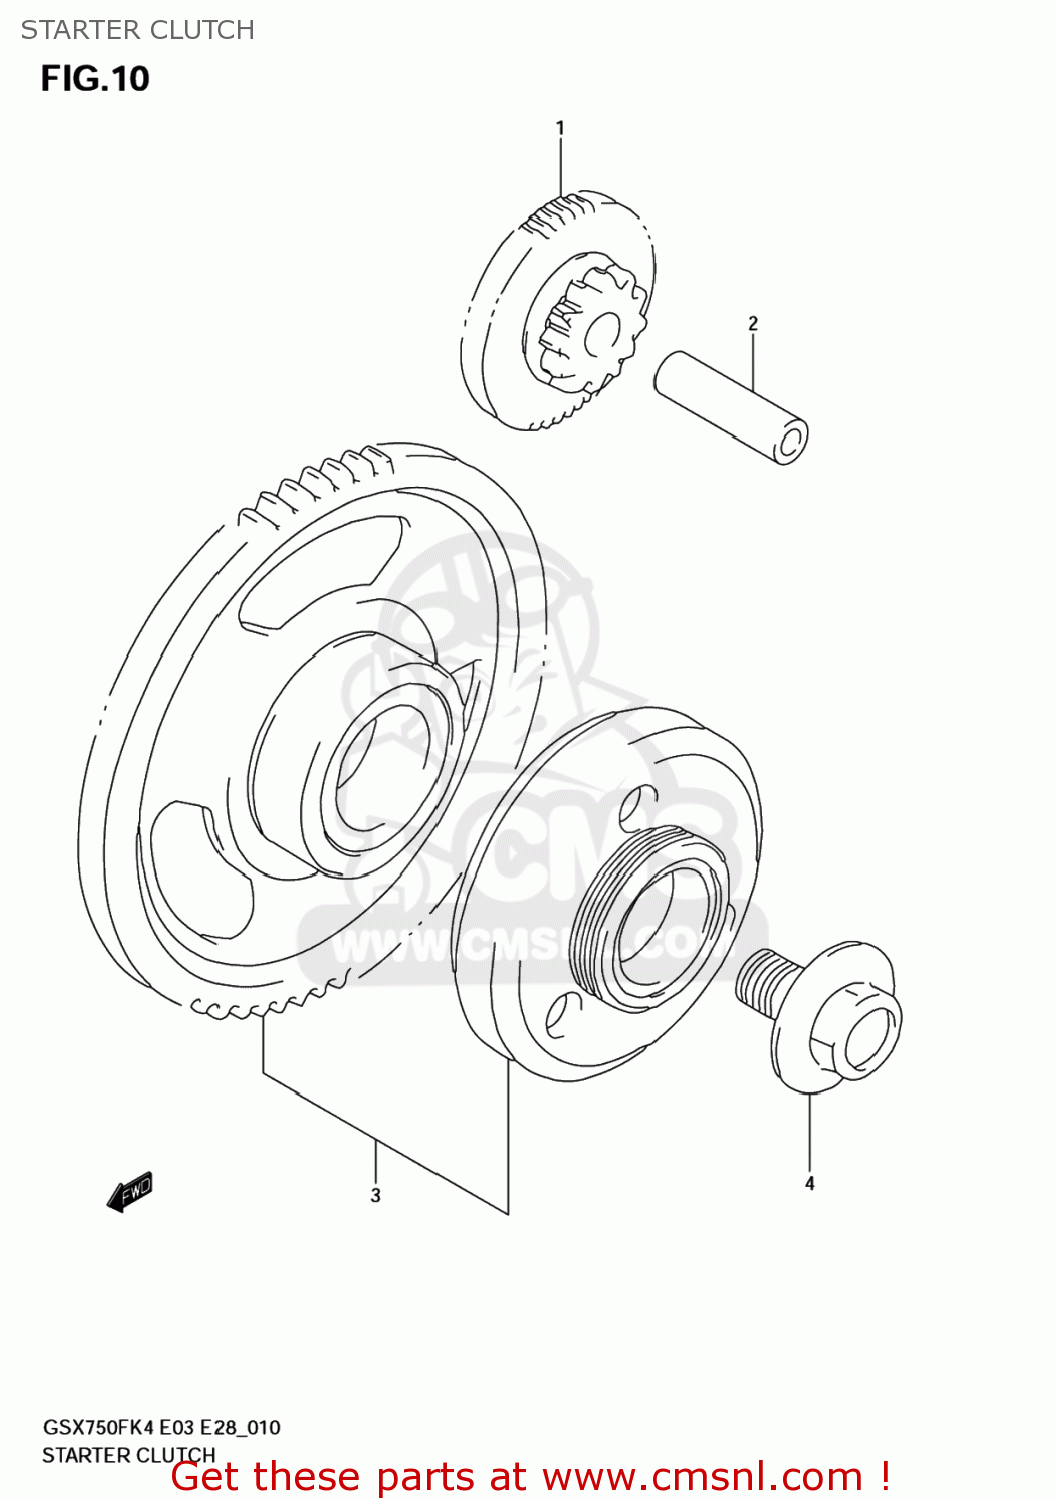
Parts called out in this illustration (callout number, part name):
1	GEAR,STARTER IDLE(NT:12,53)
2	PIN(7X11X42)
3	CLUTCH SET,STARTER
4	BOLT(14X21)
